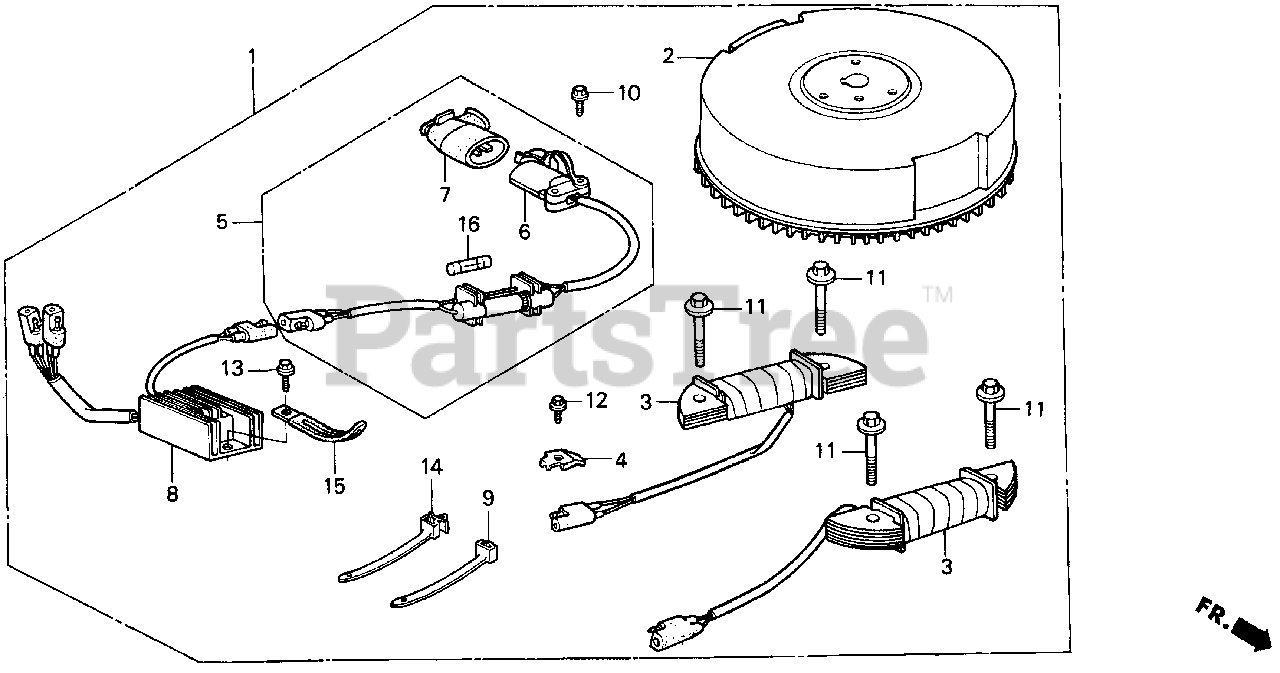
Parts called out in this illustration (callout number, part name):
1	RECEPTACLE KIT, CHARGE
2	FLYWHEEL (CHARGE)
3	COIL ASSY., CHARGE (12V-1.5A)
4	CLAMP, WIRE
5	RECEPTACLE ASSY., CHARGE Use up to Engine SN 1308874.
5	RECEPTACLE ASSY., CHARGE Use from Engine SN 1308875.
6	RECEPTACLE
7	PLUG, RECEPTACLE Use up to Engine SN 1308874.
7	PLUG, RECEPTACLE
8	RECTIFIER ASSY., REGULATOR
9	TIE, CABLE
10	BOLT, FLANGE (5X22)
11	BOLT, FLANGE (6X28)
12	BOLT, FLANGE (5X10)
13	BOLT, FLANGE (6X16)
14	BAND, CABLE
16	FUSE A (5A)
